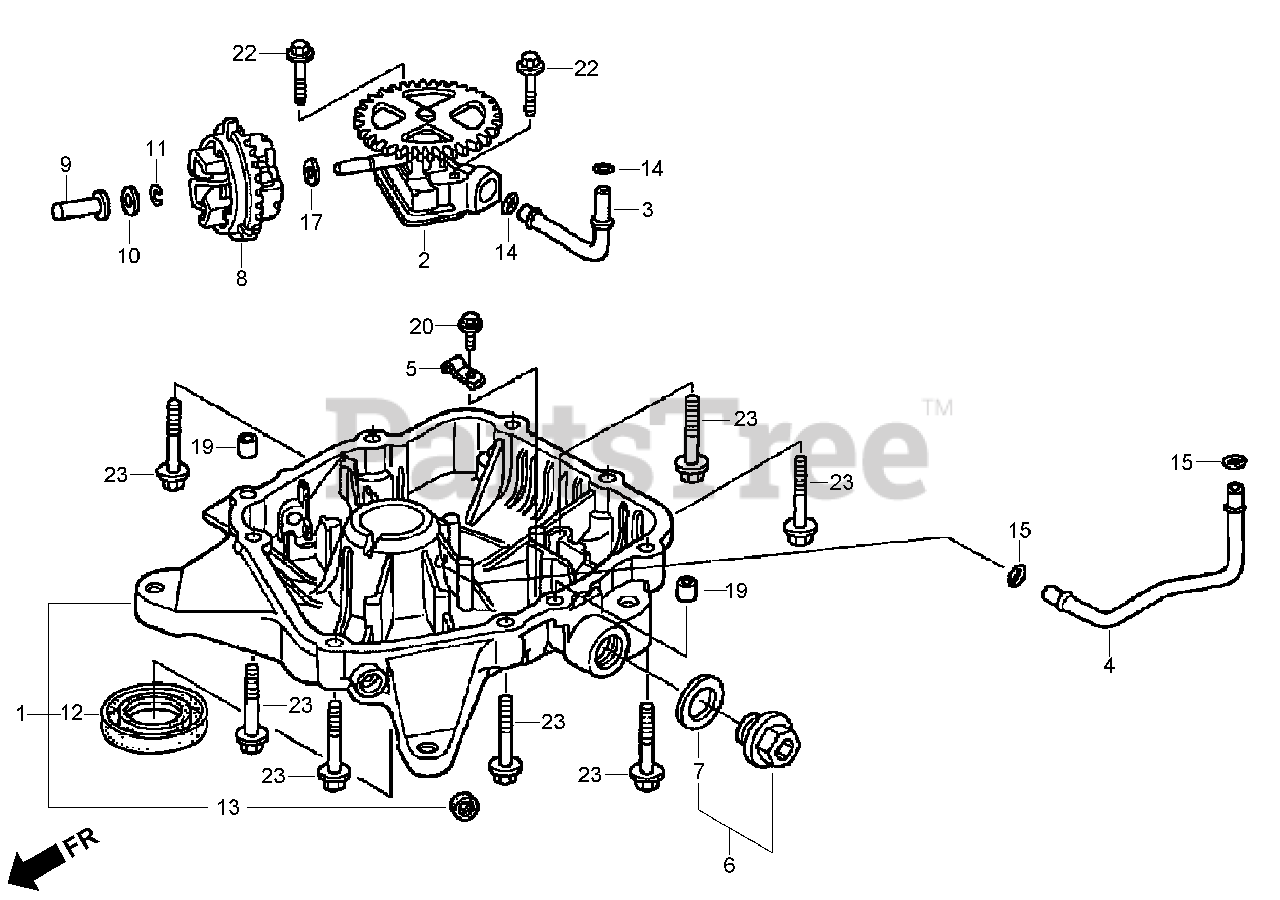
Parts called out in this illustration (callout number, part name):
1	OIL PAN ASM
2	OIL PUMP ASM
3	PIPE-PUMP, OIL
4	PIPE-SUPPLY, OIL
5	HOLDER-PIPE, OIL
6	DRAIN CAP ASM
7	GASKET-CAP, OIL FILLER
8	GOVERNOR ASM
9	SLIDER-GOVERNOR
10	WASHER (6X16)
11	CLIP-HOLDER, GOVERNOR
12	SEAL-OIL (31X50X8)
13	SEAL-OIL (10X16X4.5)
14	O-RING (7.5X2.3)
15	O-RING (5.8X2)
17	WASHER-PLAIN (6MM)
19	Pin-Dowel (8X14)
20	BOLT-FLANGE (6X12)
22	BOLT-FLANGE (6X35)
23	BOLT-FLANGE (8X40)
